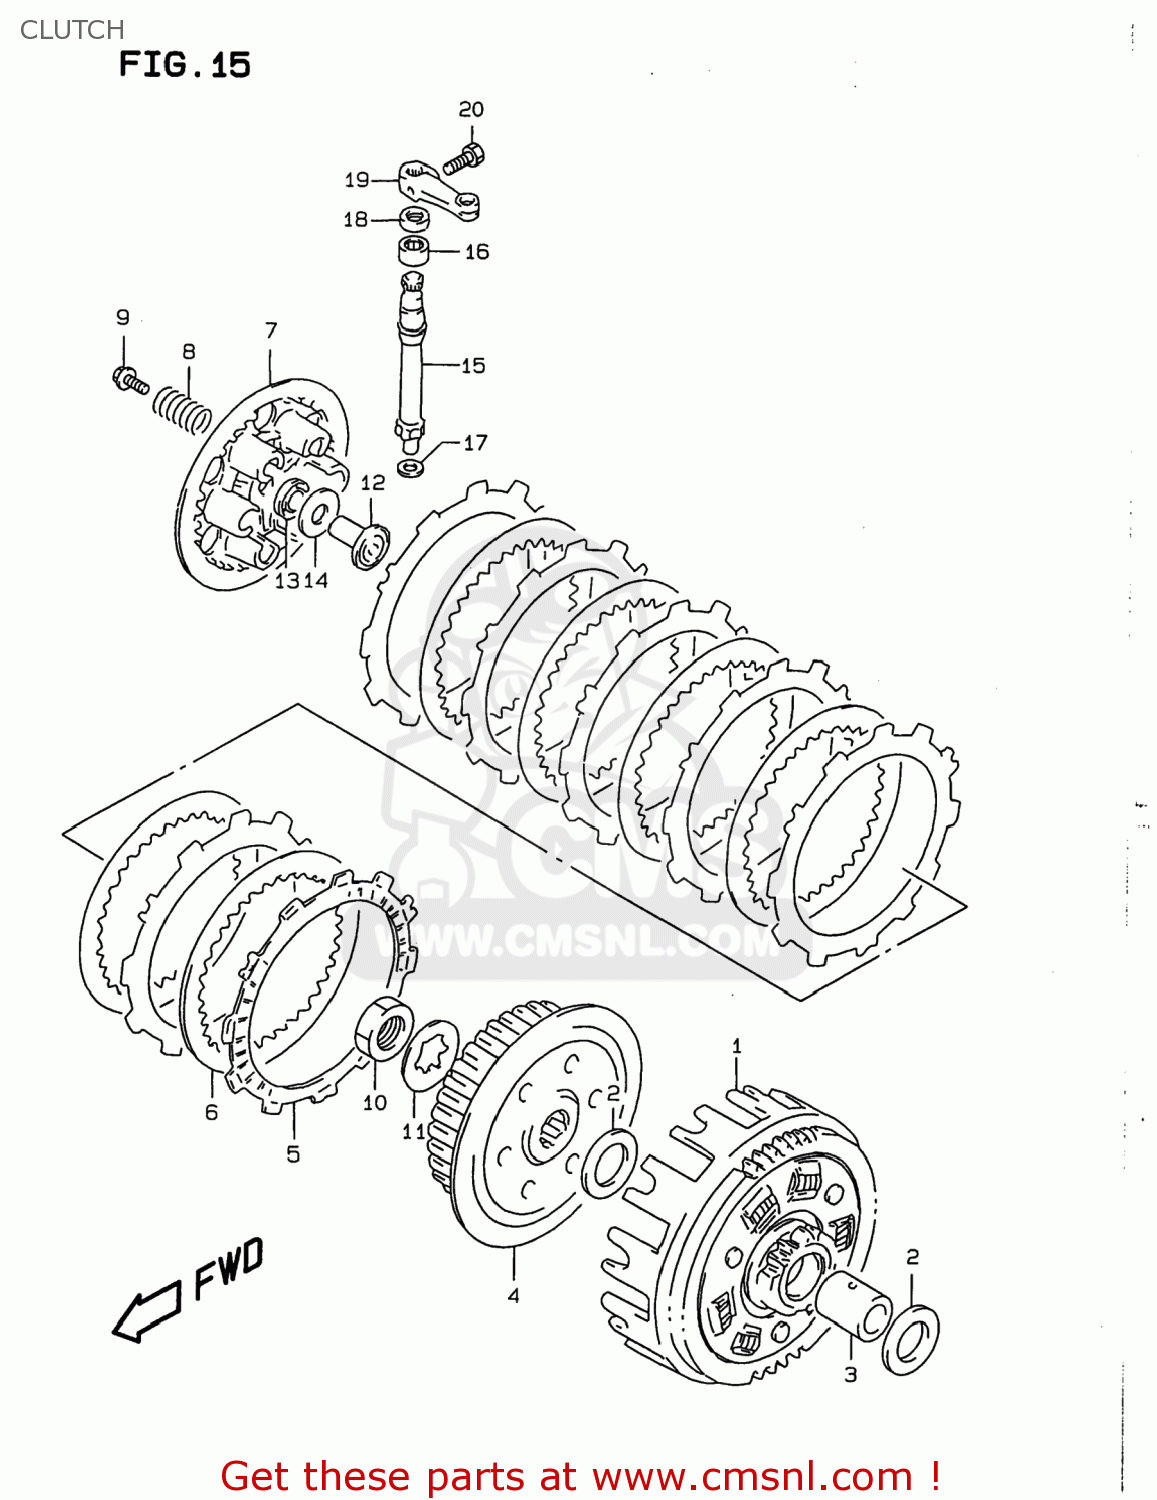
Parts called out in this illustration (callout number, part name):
1	GEAR ASSY,PRI DRIVEN(64/15
2	WASHER
3	SPACER(20X25X29)
4	HUB,CLUTCH SLEEVE
5	PLATE,CLUTCH DRIVE (NAS)
6	PLATE,CLUTCH DRIVEN(T:1.6) (NAS)
7	DISC,CLUTCH PRESSURE
8	SPRING
9	BOLT 5X16
10	NUT
11	WASHER,LOCK
12	RACK,CLUTCH RELEASE
13	BEARING(10X24X2)
14	WASHER
15	PINION,CLUTCH RELEASE
16	BEARING(12X16X10)
17	SHIM(8.8X14X1)
18	SEAL,OIL(10X17X5)
19	ARM,CLUTCH RELEASE
20	BOLT
